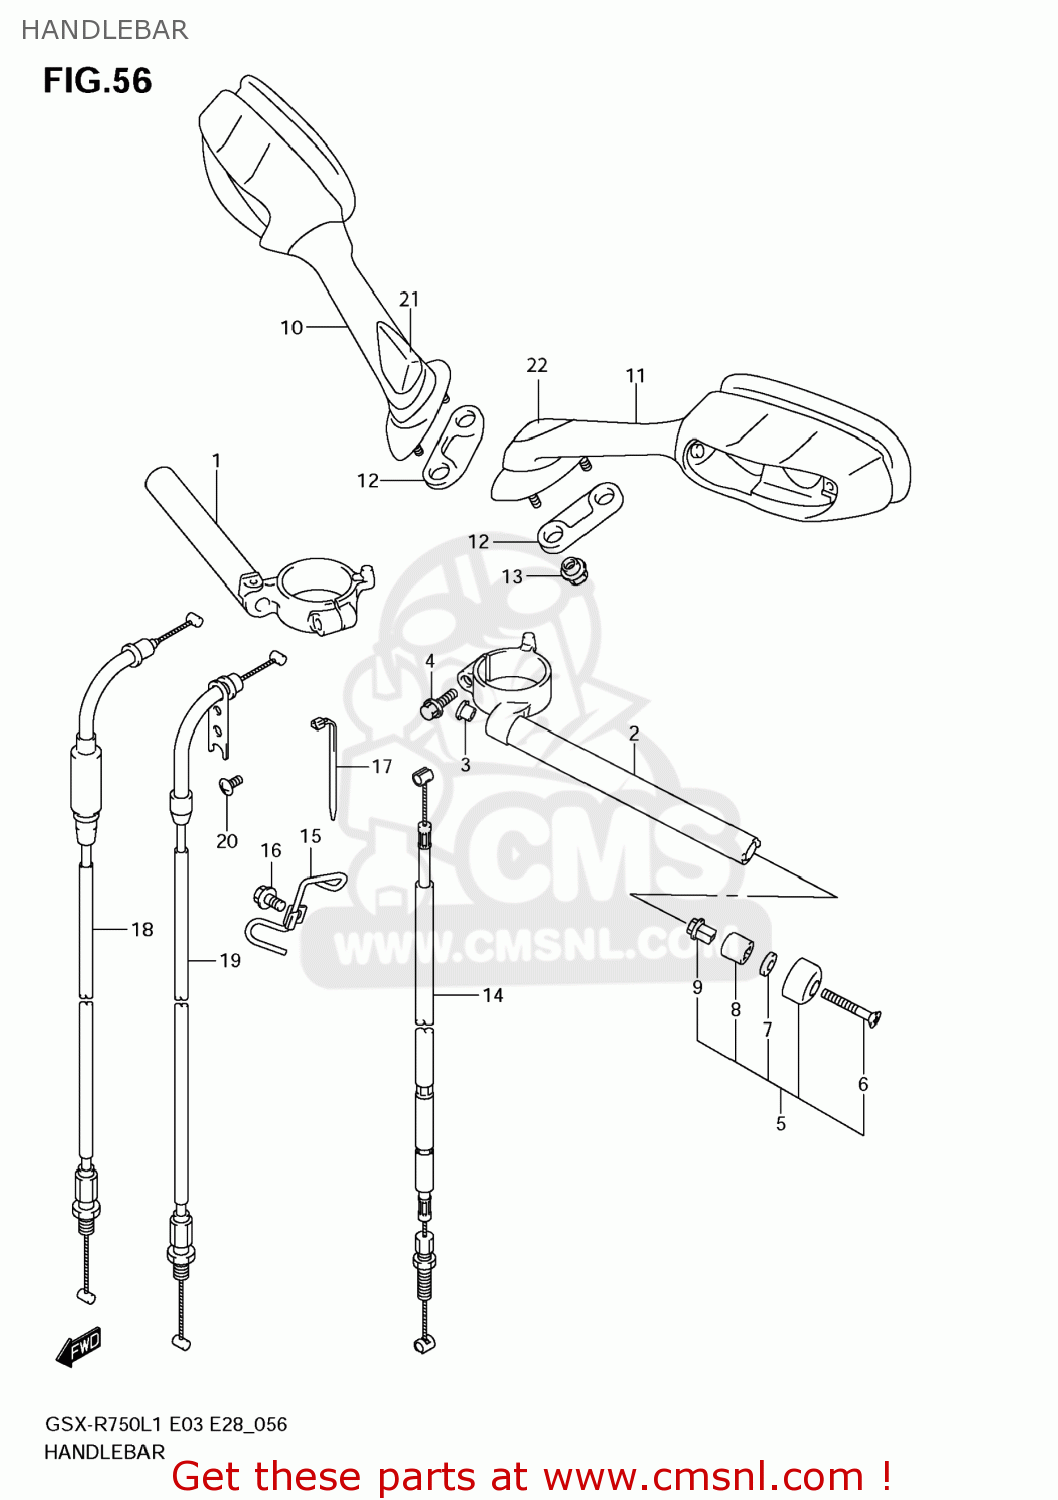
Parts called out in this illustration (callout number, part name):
1	HANDLEBAR,R
2	HANDLEBAR,L
3	CAP,HANDLEBAR
4	BOLT(8X32)
5	BALANCER SET,HANDLEBAR
6	SCREW
7	WASHER(6.5X16X4)
8	EXPANDER,HANDLE BALANCER
9	NUT,HANDLE BALANCER
10	MIRROR ASSY,RE
11	MIRROR ASSY,RE
12	CUSHION,RR VIEW MIRRROR,R
13	NUT,RR VIEW MIRROR
14	CABLE ASSY,CLUTCH
15	GUIDE,CABLE
16	BOLT
17	CLAMP(L:154)
18	CABLE ASSY,THROTTLE NO.1
19	CABLE ASSY,THROTTLE NO.2
20	SCREW(5X10)
21	CAP,R
22	CAP,L
